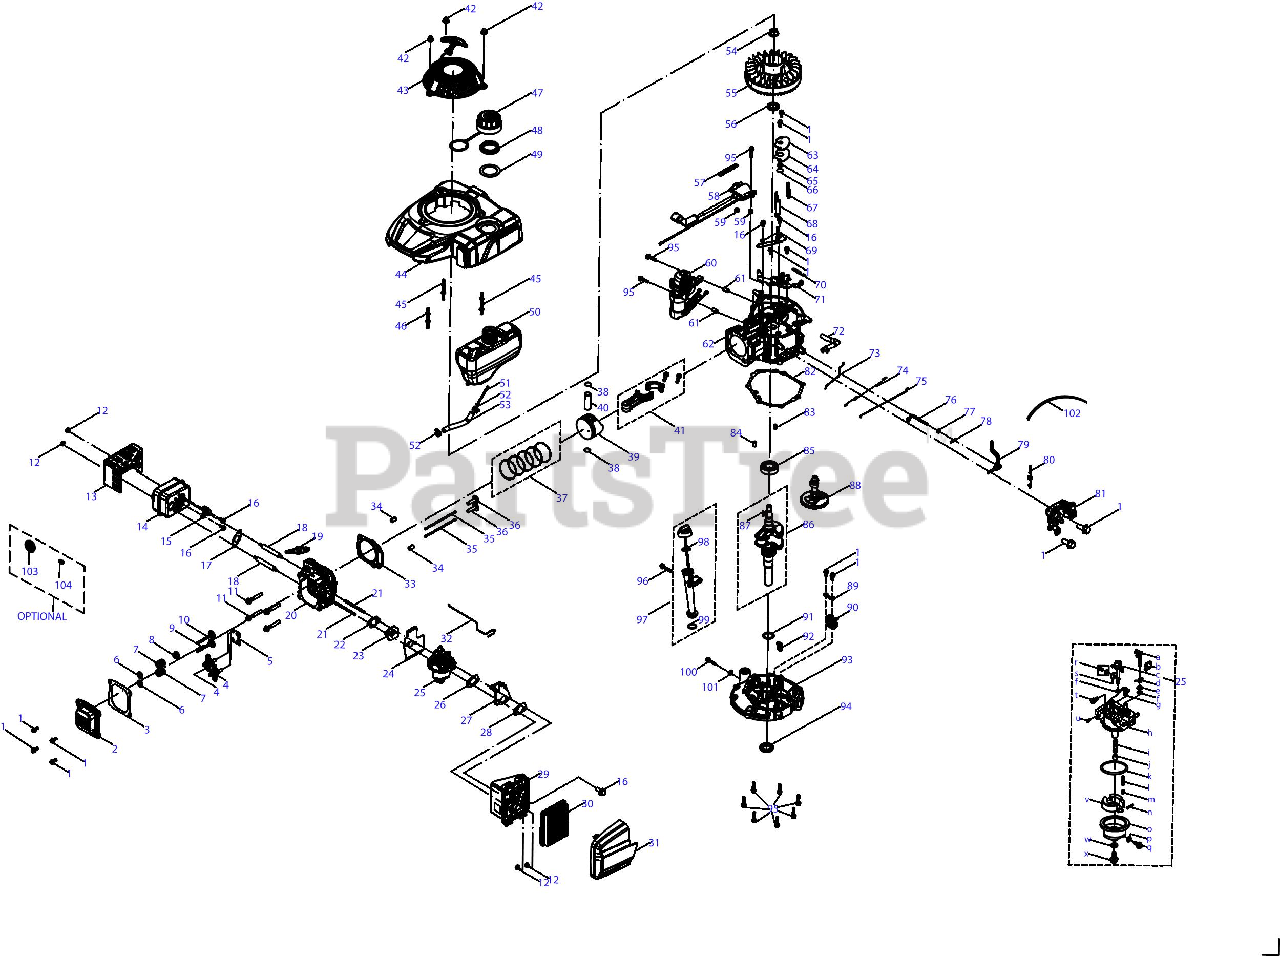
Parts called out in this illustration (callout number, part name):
1	Bolt M6x14
2	Valve Cover
3	Valve Cover Gasket
4	Rocker Arm Assembly
5	Push Rod Guide
6	Valve Spring Retainer
7	Valve Spring
8	Intake Valve Seal
9	Exhaust Valve
10	Intake Valve
11	Bolt M8x54 Cylinder Head
12	Nut M6X10
13	Muffler Shield
14	Muffler Assembly
15	Choke Thermal Control
16	Bolt M6x12
17	Muffler Gasket
18	Muffler Stud M6x98
19	Spark Plug/F5RTC
20	Cylinder Head
21	Carb Stud M6x87
22	Carburetor Insulator Gasket
23	Carburetor Insulator
24	Carburetor Gasket
25	Carburetor Assembly
26	Air Filter Bracket Gasket
27	Air Filter Bracket
28	Air Filter Base Gasket
29	Air Filter Base
30	Air Filter Element, Paper
31	Air Filter Cover
32	Temp Control Linkage
33	Cylinder Head Gasket
34	Cylinder Head Dowel Pin 10x16
35	Push Rod
36	Tappet
37	Piston Ring Set
38	Piston Pin Snap Ring
39	Piston
40	Piston Pin
41	Connecting Rod Assembly
42	Starter Acorn Nut
43	Starter Recoil Assembly
44	Engine Shroud Assembly
45	Shroud Stud M6x78.5
46	Shroud Stud M6x74
47	Fuel Cap Assembly
48	Fuel Tank Nut
49	Fuel Tank Upper Grommet
50	Fuel Tank
51	Fuel Filter
52	Fuel Hose Clamp
53	Fuel Hose
54	Flywheel Nut M14
55	Flywheel
56	Upper Crankshaft Seal
57	Flexible Clamp
58	Ignition Coil Assembly
59	Ignition Coil Spacer
60	Electric Starter Assembly (69:12)
61	Starter Housing Dowel Pin 8x8
62	Crankcase
63	Breather Cover Plate
64	Breather Gasket
65	Breather Valve Spring
66	Breather Valve
67	Breather Screen
68	Air Vane
69	Air Vane Bracket
70	Brake Spring
71	Brake Assembly
72	Breather Hose Assembly
73	Choke Linkage
74	Throttle Linkage Spring
75	Throttle Linkage
76	Governor Arm Shaft
77	Governor Seal
78	Governor Arm Shaft Cotter Pin
79	Governor Arm Assembly
80	Governor Spring
81	Throttle Control, Two Speed
82	Crankcase Cover Gasket
83	Crankcase Cover Dowel Pin 7x14
84	Crankcase Cover Dowel Pin 9x14
85	Main Bearing
86	Crankshaft Assembly
87	Flywheel Key
88	Camshaft Assembly
89	Governor Gear Mounting Plate
90	Governor Gear/Shaft Assembly
91	Crankshaft Thrust Washer
92	Oil Return Seal
93	Crankcase Cover
94	Lower Crankshaft Seal
95	Bolt M6x28
96	Bolt M6x35
97	Dipstick Assembly
98	Dipstick / Oil Fill Tube O-Ring
99	Dipstick / Oil Fill Tube O-Ring
100	Oil Drain Plug
101	Oil Drain Plug Washer
102	Plastic Tie 150Mm
103	Spark Arrestor
104	Spark Arrestor Screw
